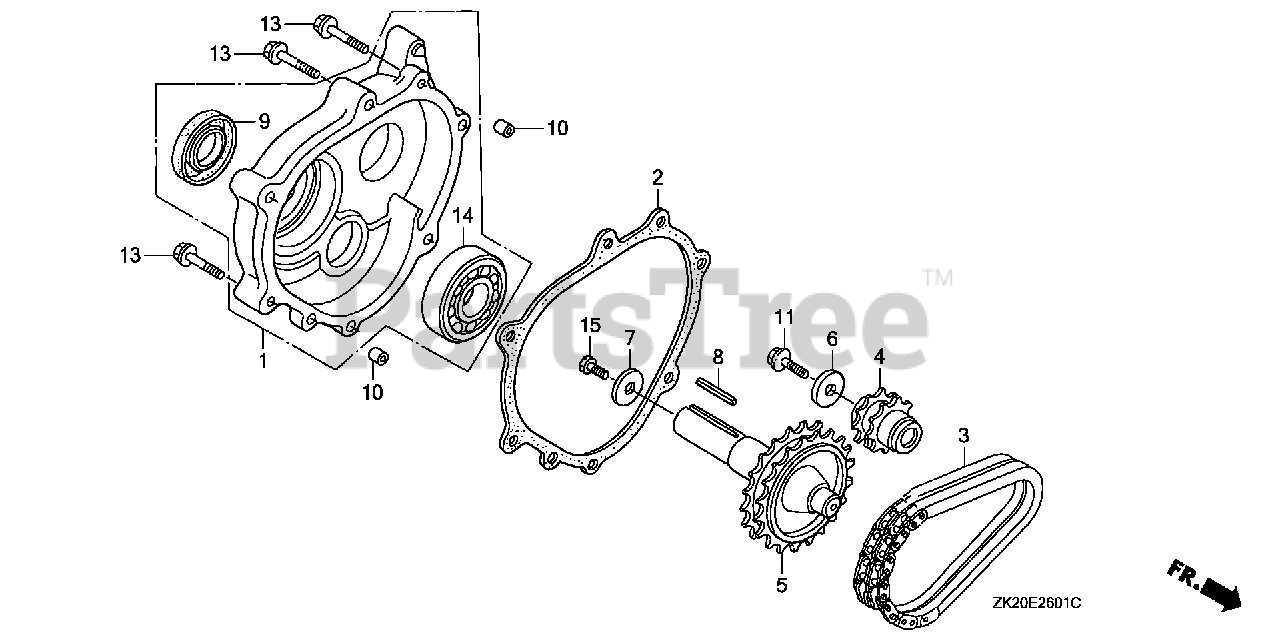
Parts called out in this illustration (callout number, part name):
1	COVER ASSY., CHAIN CASE
2	GASKET, CHAIN CASE COVER
3	CHAIN, P.T.O. DRIVE
4	SPROCKET, DRIVE (14T)
5	SHAFT, P.T.O. (28T)
6	WASHER (8MM)
8	KEY (7X7X33) (OVER SIZE) (YELLOW)
9	OIL SEAL (30X46X8)
10	PIN, DOWEL (8X14)
11	BOLT, FLANGE (8X25)
13	BOLT, FLANGE (8X40)
14	BEARING, RADIAL BALL (6206)
